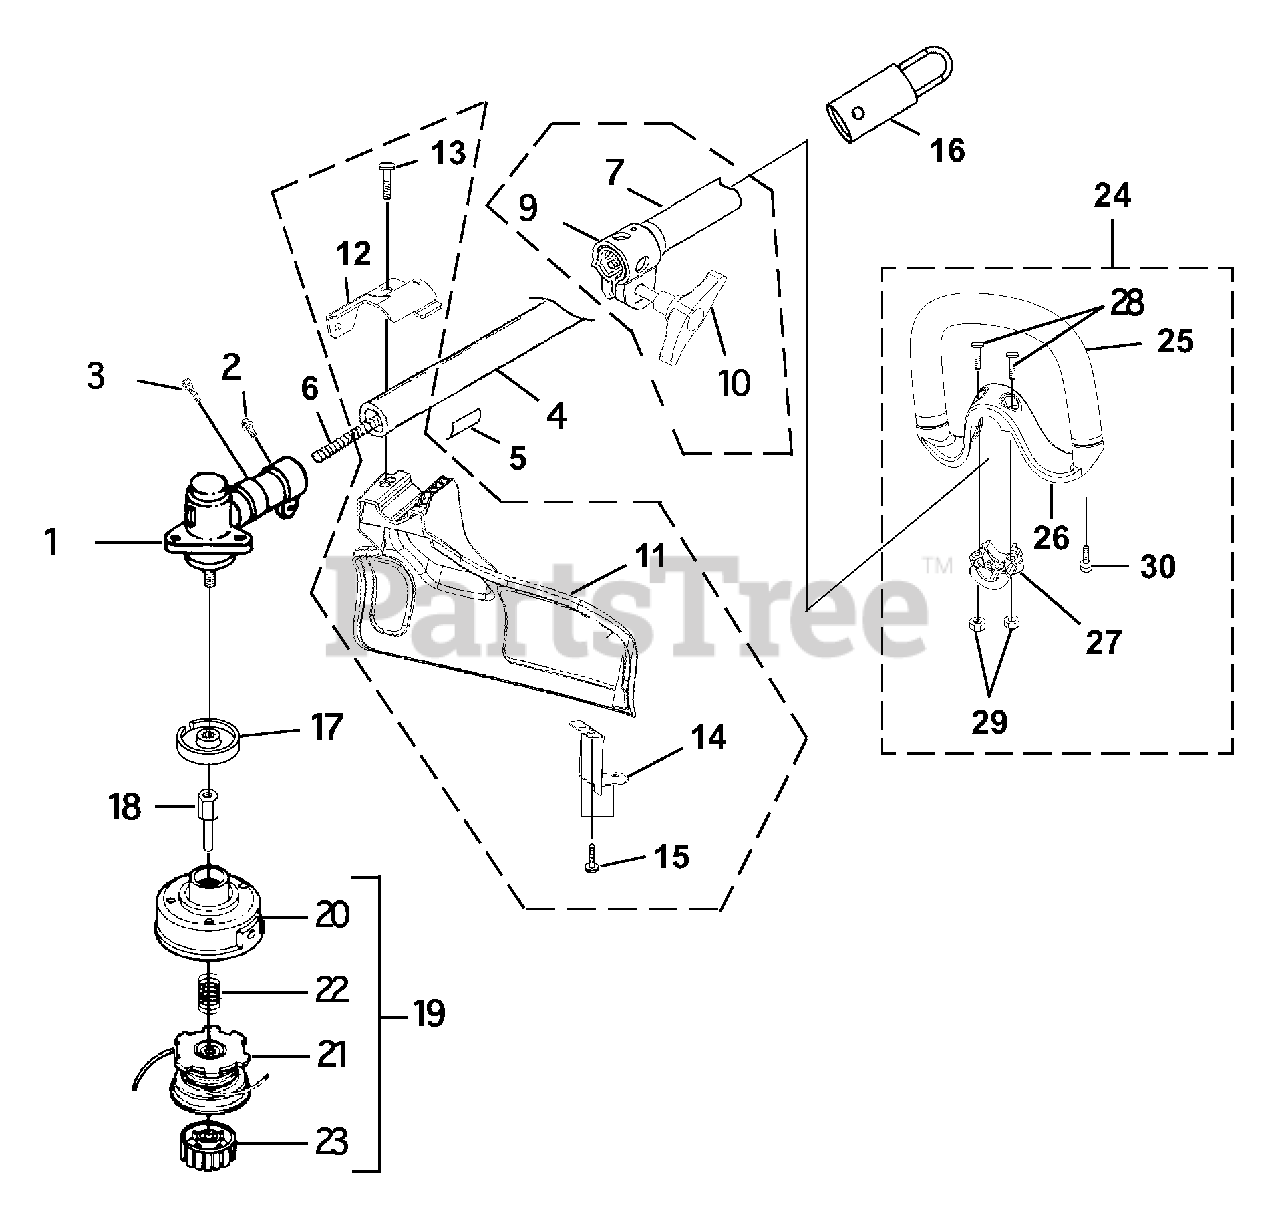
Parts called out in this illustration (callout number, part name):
1	GEAR HEAD
2	Screw, Cap Hd. (1/4-20 X 1.25")
3	Screw-Hex Hd. (10-24 x .625")
4	DRIVESHAFT HOUSING (Lower)
5	DECAL-Warning
6	SHAFT-Flexible
7	DRIVESHAFT HOUSING (Upper)
9	COUPLER ASSEMBLY
11	GRASS SHIELD
12	CLAMP - Grass Shield
13	SCREW-Hex Hd. (1/4-20 x 1.25")
14	BLADE-Cut-off
15	SCREW-Pan Hd. (8-16 x 1/2")
16	END CAP
17	WASHER-Flanged
18	ADAPTER-Stringhead
19	STRINGHEAD-Complete (.095") Orange
20	HOUSING & EYELET (Dual Line)
21	SPOOL & STRING (.095") Orange
22	SPRING-Compression
23	RETAINER-Spool (L.H. Thread)
24	HANDLE-Complete
25	HANDLE W/Grip
26	CLAMP - "M"
27	CLAMP-Assist Handle
